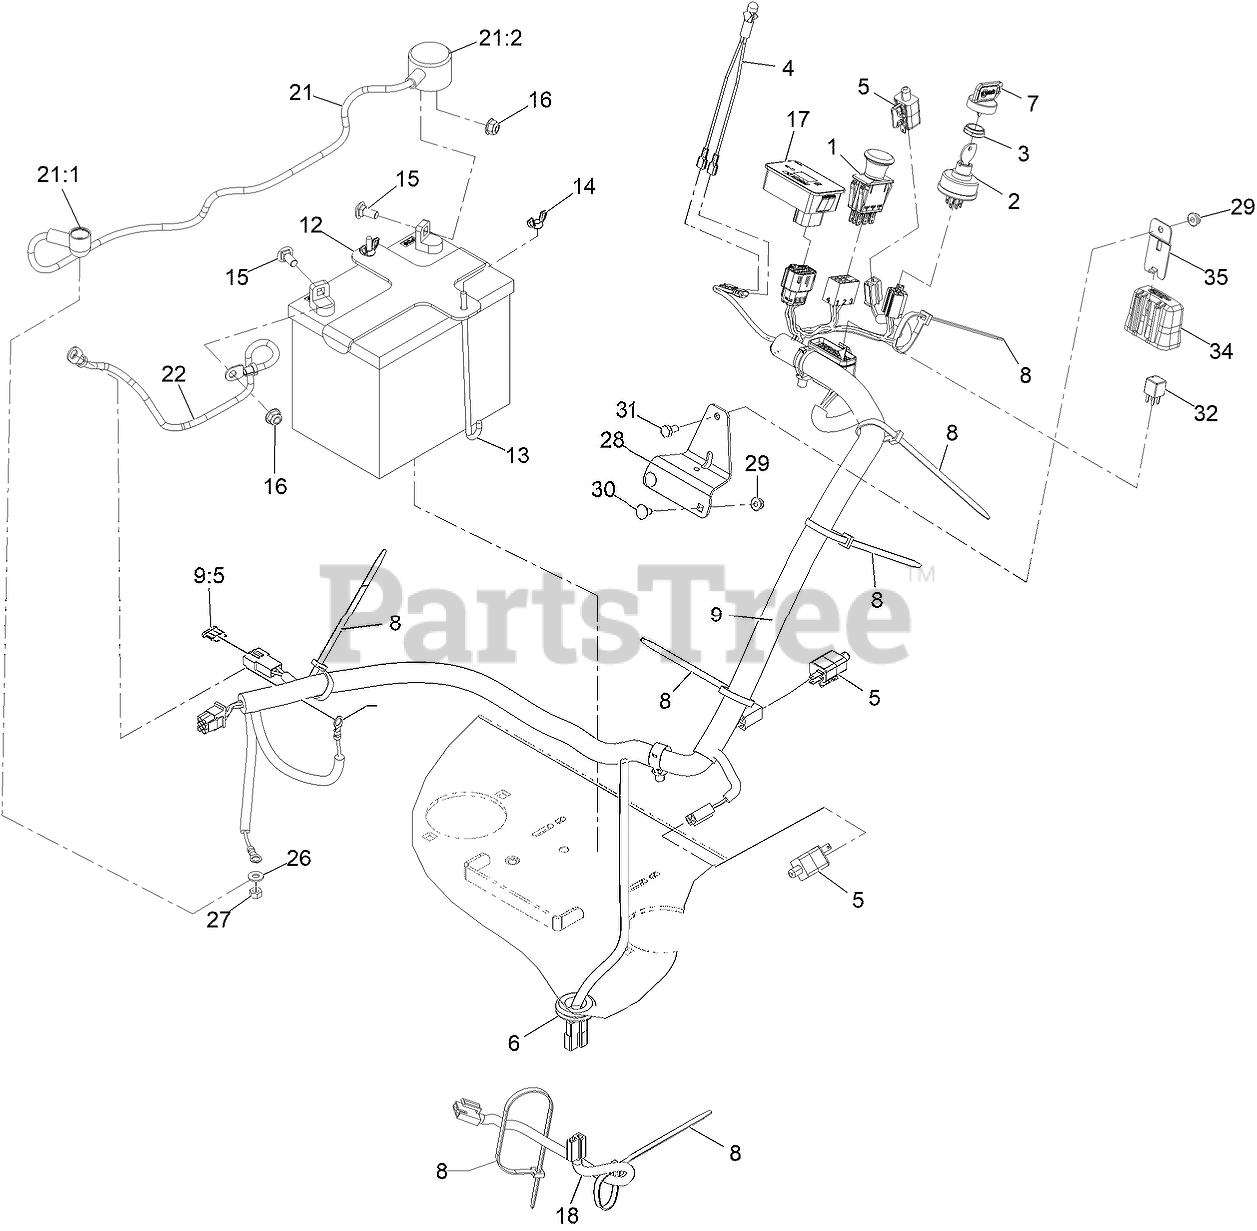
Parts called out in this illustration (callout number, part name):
1	SWITCH-PTO
2	SWITCH, KEY START
3	NUT-SWITCH, IGNITION
4	INDICATOR-LED, RED
6	GROMMET
7	KEY-IGNITION
8	TIE-CABLE
9	HARNESS-WIRE
9:5	FUSE-BLADE TYPE, 20 AMP
12	BRACKET, BATTERY HOLD DOWN
13	BOLT-HOLDDOWN
14	WINGNUT
15	BOLT-CARR
16	NUT-HF, NI
17	MODULE-HOUR METER
18	HARNESS-CLUTCH PIGTAIL
21	POSITIVE BATTERY CABLE AS
21:1	INSULATOR-SOLENOID
21:2	INSULATOR-BATTERY
26	WASHER-FLAT
27	NUT-HEX
28	BRACKET-MOUNTING, FUSEBLOCK
30	SCREW-CARR
31	SCREW-HH
32	RELAY-MICRO
34	COVER-BLOCK, FUSE
35	CLIP-MOUNTING
